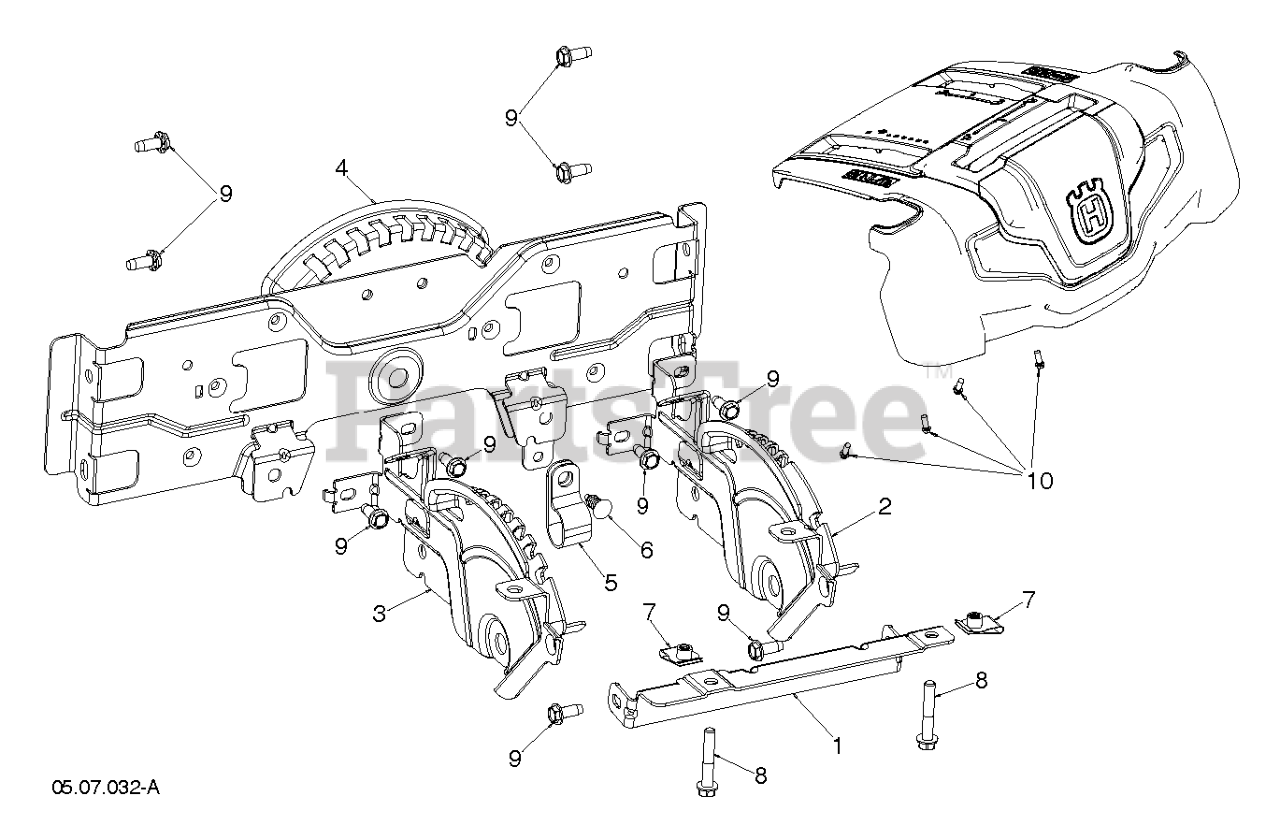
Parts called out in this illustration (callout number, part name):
1	HANDLE.ASM.LOWER.TRACK.GREY
2	SUPPORT.WELDMENT.ROTATOR.BLACK
3	PLATE.FOOT.ASM.SNOW
4	SPRING.EXTENSION.TRACK.SNOW
5	SHOULDERBOLT5/1618
6	NUT.CENTERLOCK.5/16-
7	SCREW.3/8-16
8	SCREW, 3/8-16X3/4
9	BOLT.5/16HEX.WHS.HD
10	FOOT.ADJUST.PLATE.GUIDE.RH.SNO
11	FOOT.ADJUST.PLATE.GUIDE.LH.SNO
12	TRACK.FOOT.ADJ.ASM.SNOW
13	TUBE.ANTI-ROTATE.TRACK
15	BOLT.HEX.FINISHED.1/4-20
16	LOCKNUT.NYLOC.1/4-20
17	SCREW THDROL 3/8-16 X 1-1/2
